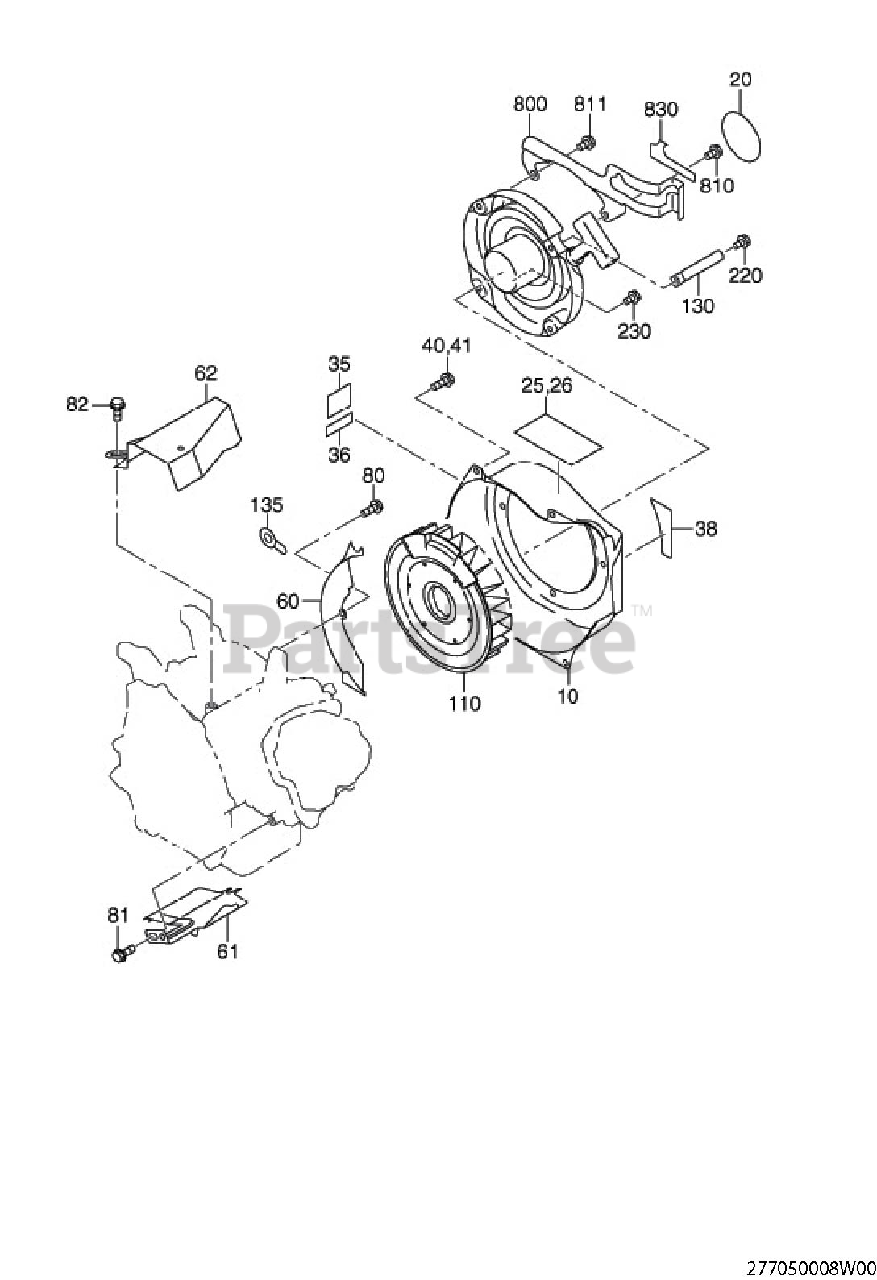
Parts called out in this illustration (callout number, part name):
10	BLOWER HOUSING CP
20	LABEL,TRADEMARK
38	LABEL(FUEL COCK)
60	BAFFLE 1 CP, CASE
61	BAFFLE 2, HEAD
110	COOLING BLOWER
220	BOLT AND WASHER
810	SCREW AND WASHER
811	SCREW AND WASHER
830	LABEL(SP170-TTI)
